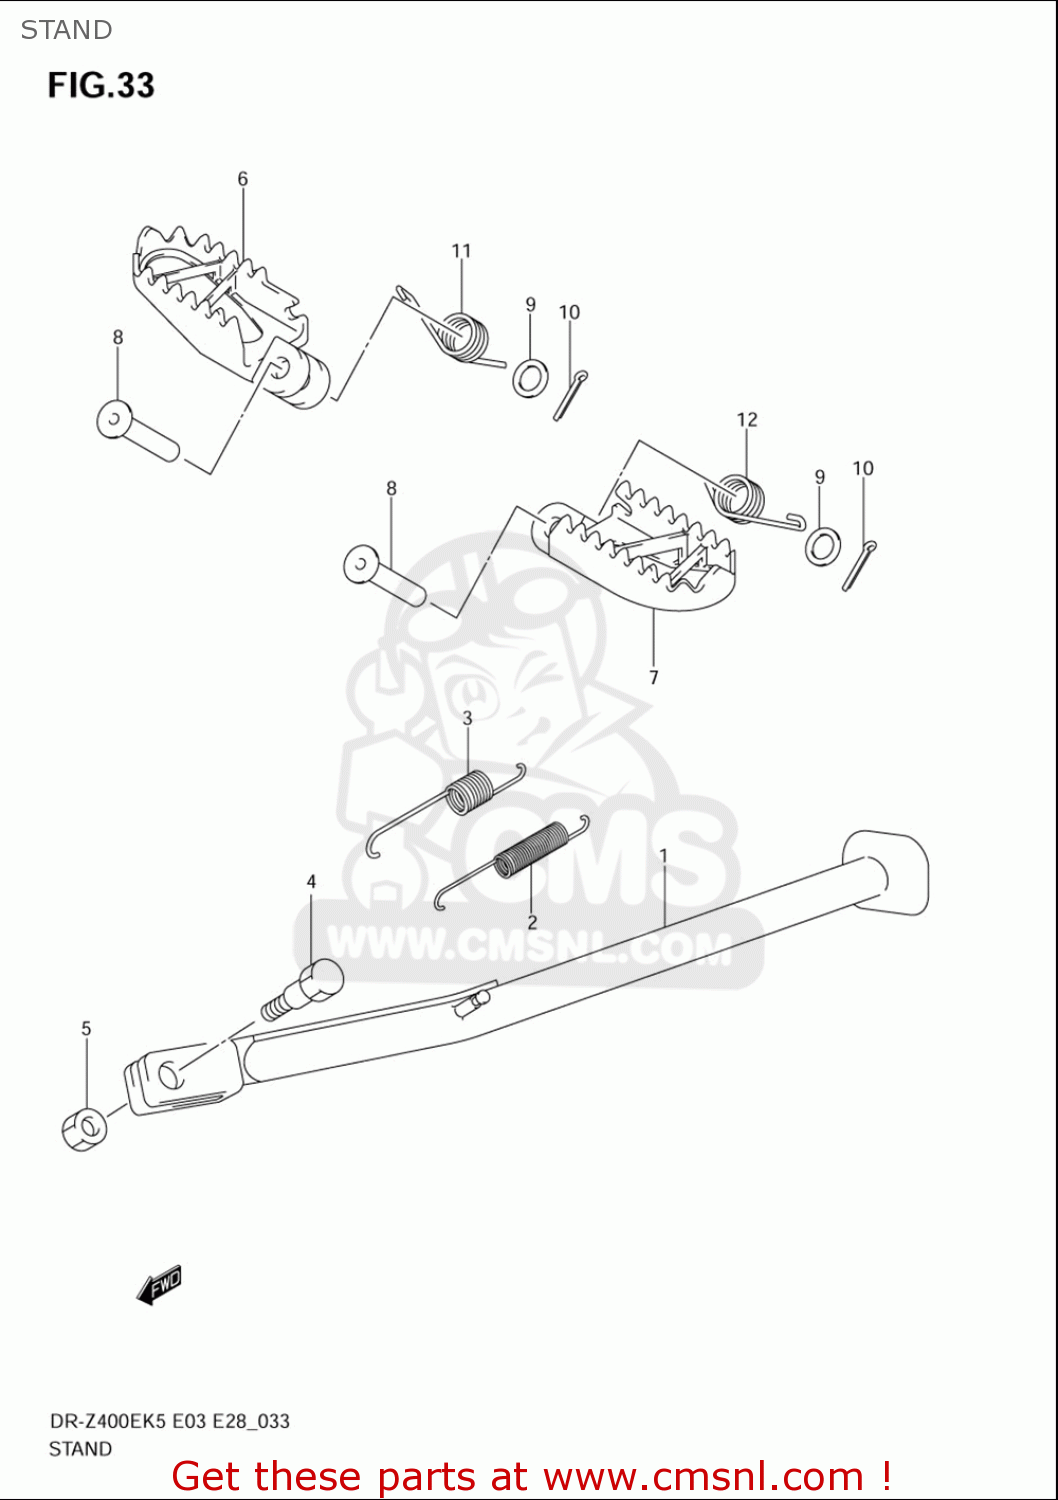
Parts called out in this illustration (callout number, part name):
1	STAND,PROP
2	SPRING
3	SPRING
4	BOLT(10X33)
5	NUT,PROP STAND
6	FOOTREST,R
7	FOOTREST,L
8	PIN(10X41.5)
9	WASHER
10	PIN
11	SPRING
12	SPRING
